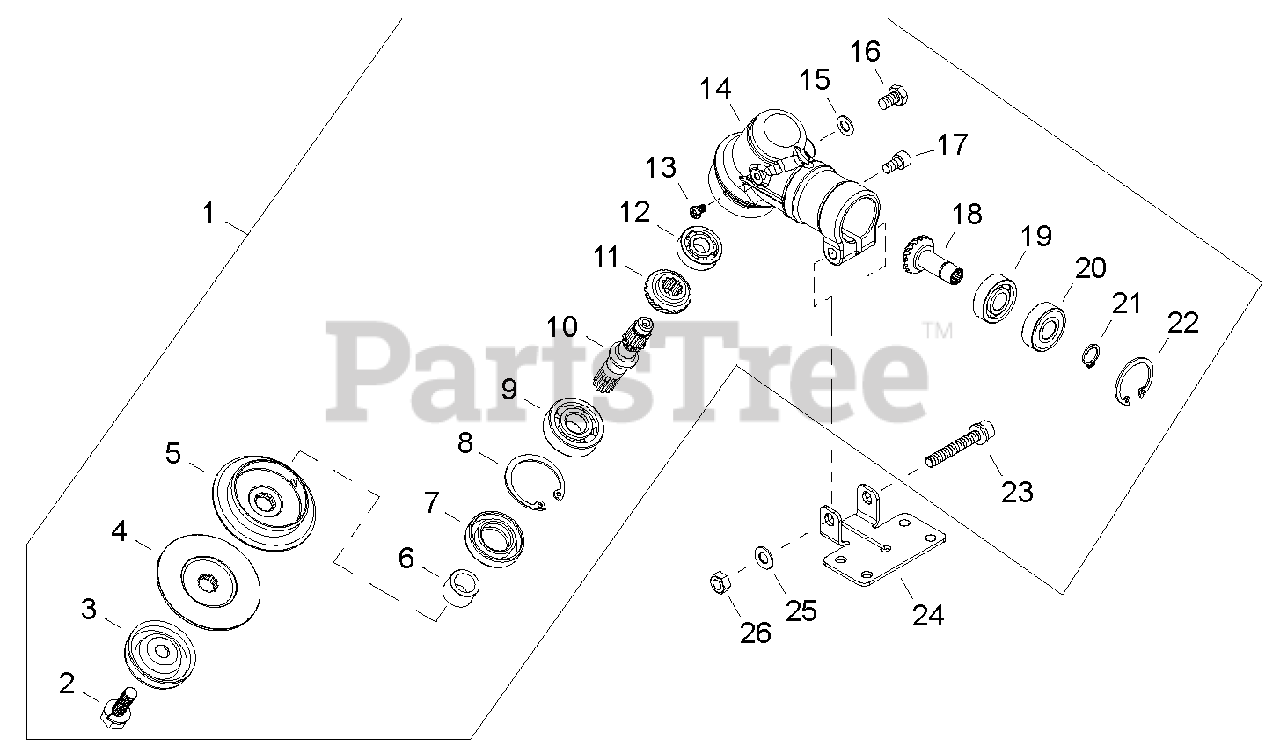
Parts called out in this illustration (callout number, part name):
1	GEAR CASE ASSY
2	BOLT M8×22
3	GUARD, BOLT
4	PLATE, ADAPTOR - LOWER
5	PLATE, ADAPTOR - UPPER
6	SPACER
7	SEAL, OIL
8	RING, SNAP Ø32
9	BEARING, BALL 6201C
10	SHAFT, GEAR
11	GEAR, BEVEL
12	BEARING, BALL 609
13	SCREW M4×6
14	CASE, GEAR
15	WASHER 6.5×11.5×0.8
16	BOLT M6×10
17	BOLT M5×10
18	PINION, BEVEL Ø8
19	BEARING, BALL 6001
20	BEARING, BALL 6000Z
21	RING, SNAP Ø10
22	RING, SNAP Ø26
23	BOLT M6×40
24	PLATE, SHIELD MOUNTING
25	WASHER 6.5×13×1
26	NUT, HEX M6
